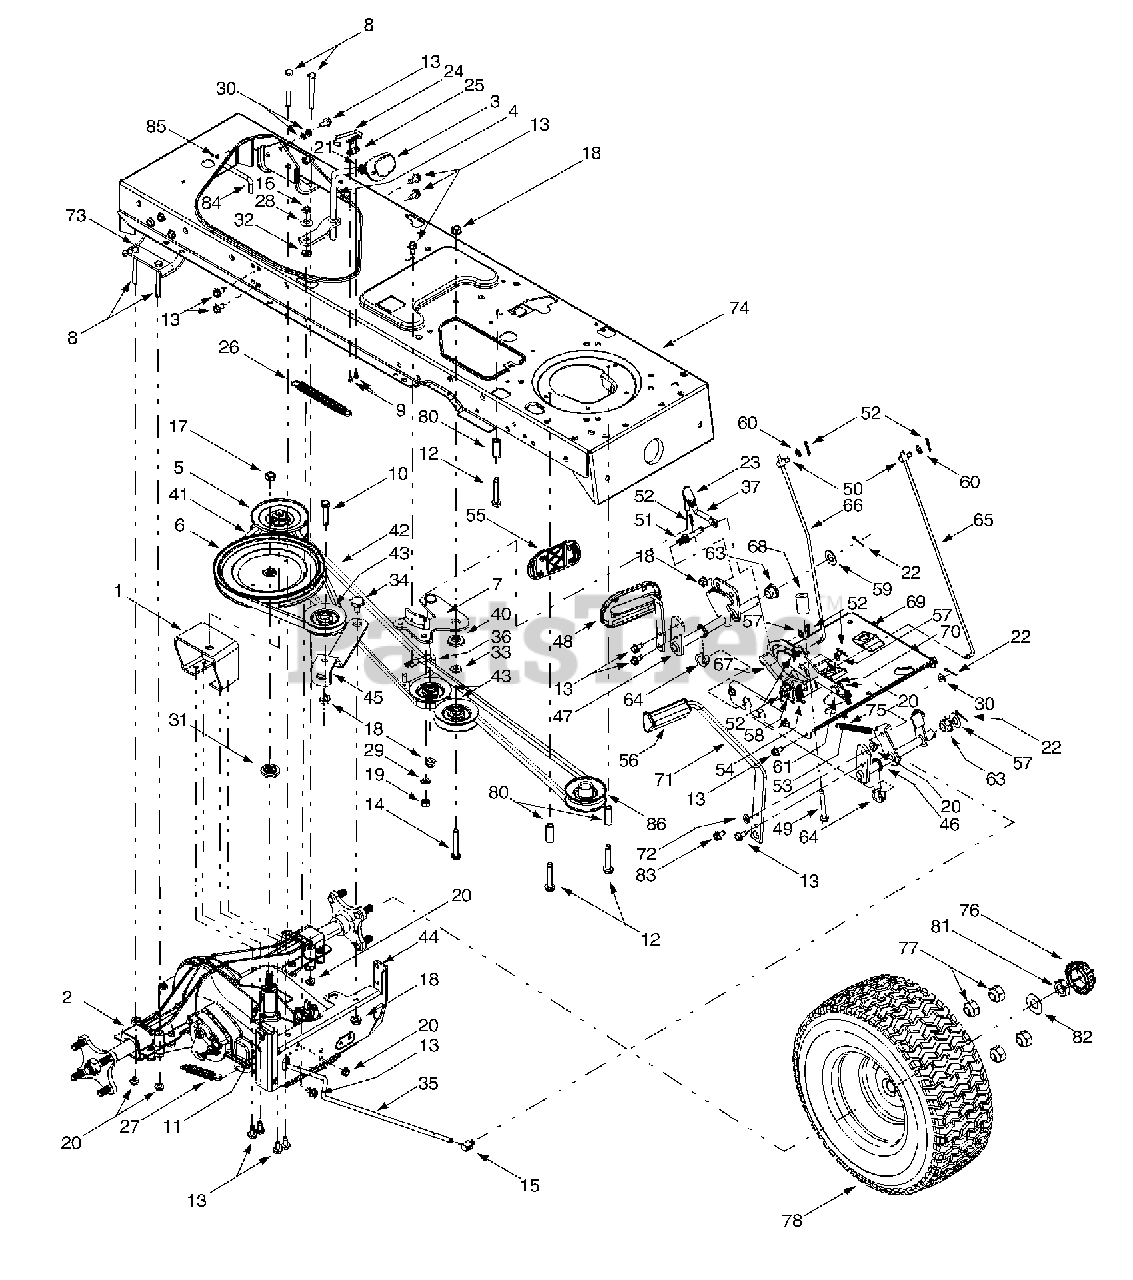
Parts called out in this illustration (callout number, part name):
1	Variable-speed Bracket Assembly
2	Two-speed Transmission Assembly
3	Shfter Knob
4	Shift Lever
5	Variable-speed Pulley Assembly
6	Transmission Pulley, 8.5
7	Double-idler Bracket
8	Hex Cap Screw, 5/16-18 x 2.75
9	Self Tapping Screw, #8-18 x .5
10	Hex Cap Screw, 3/8-16 x 1.75
11	Hex Cap Screw, 5/16-18 x 1.5
12	Self-tapping Screw, 1/4-20 x 1.25
13	Self Tapping Screw, 5/16-18 x .625
14	Hex Cap Screw, 3/8-16 x 2.25
15	Ferrule, 5/16 x .312 Dia.
16	Hex Jam Nut, 3/8-16
17	Hex Flange Nut, 7/16-20
18	Flange Lock Nut, 3/8-16
19	Hex Nut, 3/8-16
20	Flange Lock Nut, 5/16-18
21	Hex Jam Nut, 3/8-16
22	Cotter Pin
23	Ball Joint, 3/8-24
24	Spring Switch
25	Insulator Nut Plate
26	Extension Spring, .62 Dia. x 6.12
27	Extension Spring, .59 OD x 4.0
28	Bell Washer, .401 x .870 x .063
29	Lock Washer, 3/8
30	Flat Washer, 5/16
31	Pulley Hub, 1/2 Spline
32	Flat Washer, .44 x .75 x .06
33	Flat Washer, .407 x .812 x .135
34	Shoulder Screw, .625 Dia. x .21
35	Brake Rod
36	Belt Guard
37	Idler Adjustment Rod, 3/8
38	Self-tapping Screw, 1/4-20 x 1.75
39	Transmission Belt Guard Rod
40	Shoulder Spacer, .380 ID
41	Variable-speed Belt
42	Drive Belt
43	Flat Idler, 2.75 OD
44	Transmission Torque Bracket
45	Idler Bracket
46	Brake Control Shaft Assembly
47	Speed Control Shaft Assembly
48	Drive Pedal Assembly
49	Self Tapping Screw, 5/16-18 x 2.5
50	Ferrule, 1/4-20
51	Pin, 3/8-16 x 2.43
52	Cotter Pin
53	Compression Spring, .34 OD x 1.0
54	Extension Spring, .5 OD x 1.41
55	Drive Pedal Pad
56	Brake Pedal Pad
57	Flat Washer, .281 x .5 x .0625
58	Flat Washer, 9/32 x 1/2 x 1/16
59	Flat Washer, .64 x 1.24 x .06
60	Flat Washer, .344 x .062 x .03
61	Shoulder Screw, .437 x 1.62
62	Shoulder Screw, .5 x .434
63	Hex Flange Bearing
64	Split Hex Flange Bearing
65	Cruise Control Rod
66	Brake Lock Control Rod
67	Cruise Latch
68	Spacer, 5/16 x 1.54
69	Steering Support Bracket
70	Drive Lockout Bracket
76	Hub Cap
77	Lug Nut, 7/16-14
78	Wheel Assembly Complete, 23 x 9.5 x 12
79	Split Spacer, .25 x .37 x 1.32
80	Spacer, .372 x .26 x 1.03
81	Jam Nut, 3/4-16
82	Flat Washer, .78 x 1.59 x .06
83	Hex Screw, 5/16-18 x .75
84	Transmission Belt Guard Rod
85	Self Tapping Screw,1/4-20 x .5
86	Engine Pulley, 3.56"
